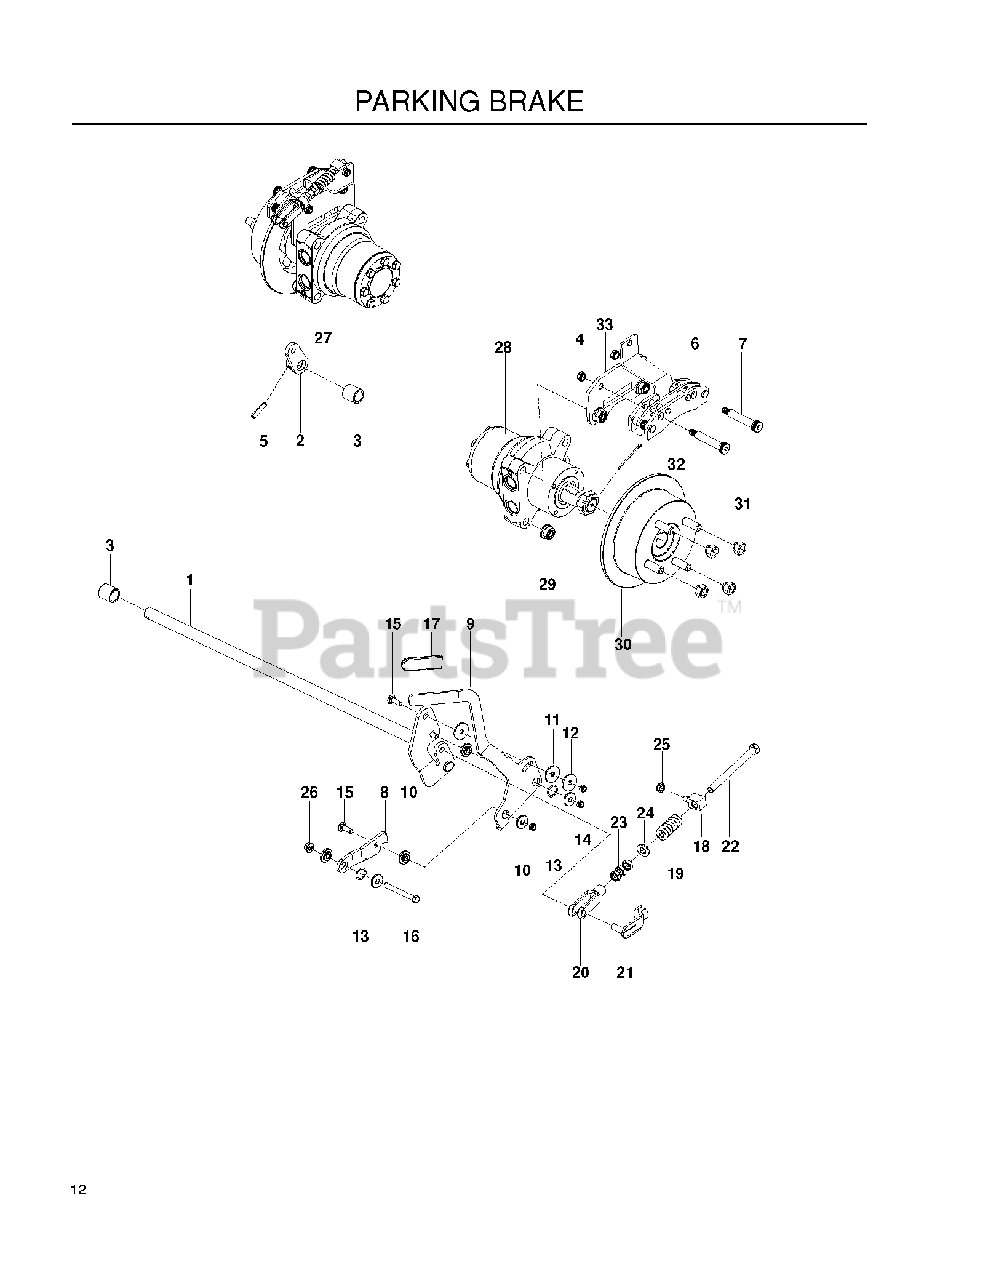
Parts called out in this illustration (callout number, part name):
1	SHAFT, BRAKE WLDMT
2	ARM, RT BRAKE
3	BUSHING, SLEEVE 3/4 X 1.0
4	NUT HEX 3/8-16 NYLON, THIN
5	5/16 DIA ROLL PIN
6	CALIPER
7	BOLT, SHOULDER, 1/2 X 2.25
8	LINK, FOLLOWER
9	LEVER.BRAKE.BLACK
10	BUSHING, BRAKE
11	WASHER, FRICTION, 1/8
12	CONE WASHER
13	WASHER, .825 X 1.087, WAVE
14	NUT HEX 3/8-16 NYLON, THIN
15	RHSNB 3/8-16 X 1-1/4
16	HCS 3/8-16 X 3-1/4 GR5 ZD
18	SWIVEL, BRAKE
21	PIN, CLEVIS SPRING, 3/8
22	HCS 3/8F X SPECIAL
23	NUT 3/8-24 JAM
24	WASHER 3/8 SAE FLAT
25	5/16-18 THIN PROF NY
26	NUT 3/8-16 HEX FLG NYLOC ZD
27	MOTOR, TL0310, RT
28	MOTOR, TL0310, LT
29	NUT, 1/2-13 HEX FLG NYLOC ZD
30	HUB, DISC BRAKE, W/STUDS
31	LUG NUT 1/2F
32	COTTER PIN 1/8 X 2
33	PLATE, CALIPER
